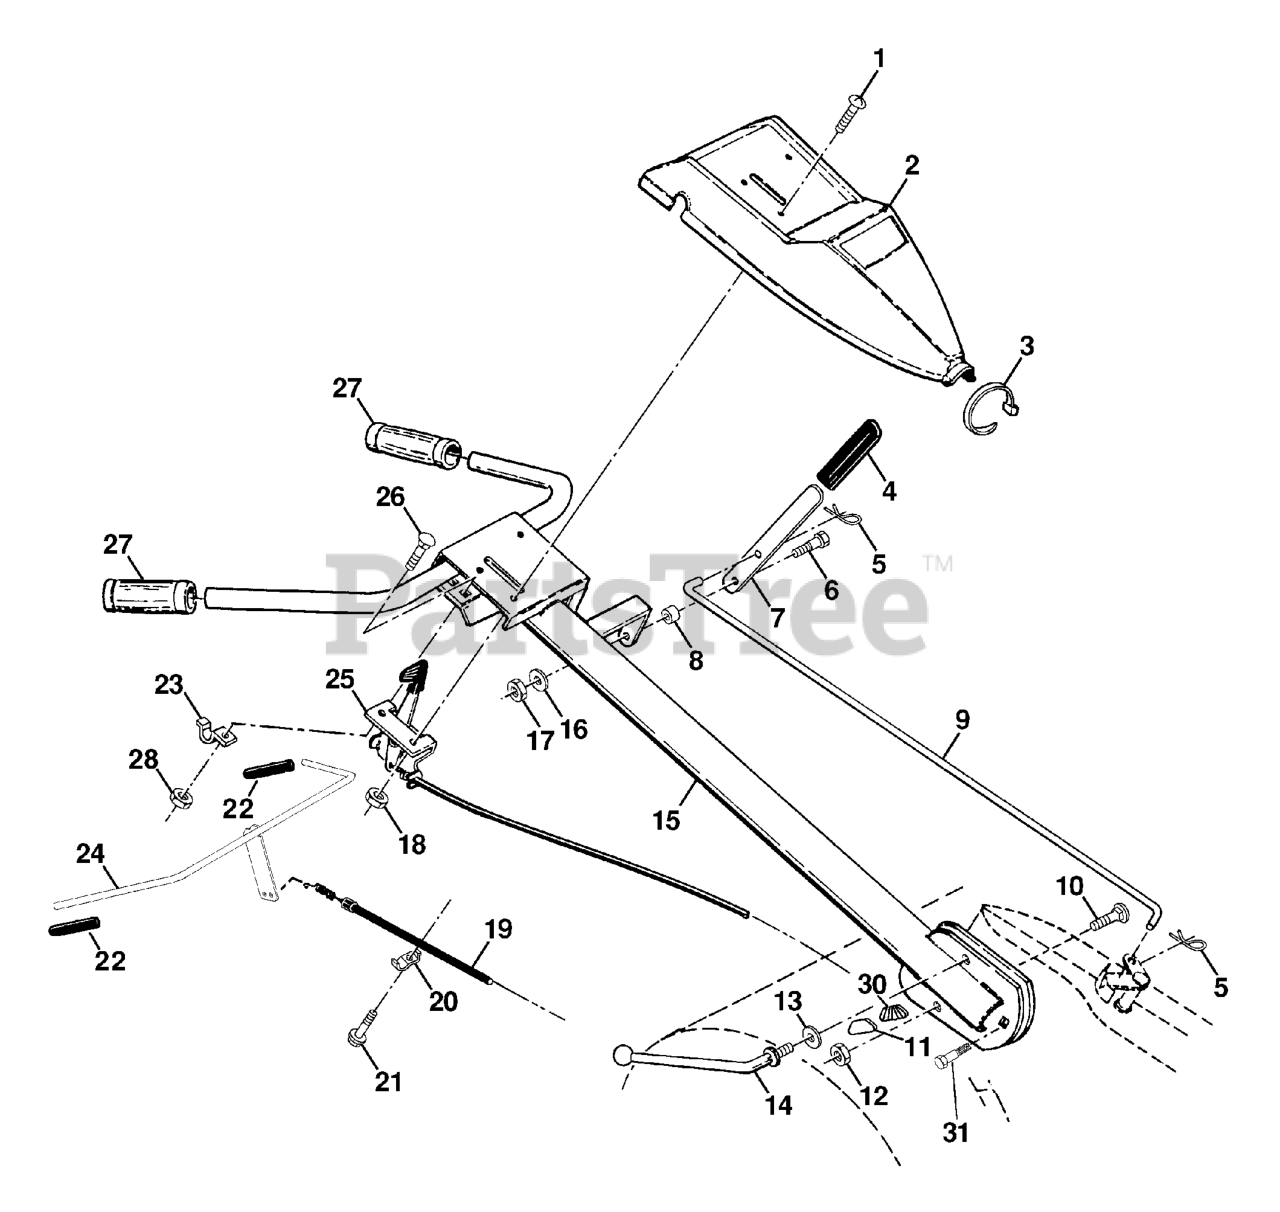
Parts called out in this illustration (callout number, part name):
1	SCREW.PNHD.10-24
3	TIE CABLE CRT
4	GRIP T
5	RETAINER M
6	SHOULDER BOLT ST
7	SHIFT HANDLE CRT
8	GROMMET.RUBBER.CRT.TILLER
9	ROD.SHIFT.YARD PRO.UNIVERSAL.
10	BOLT D
11	LOCK.HANDLE.CRT
12	LOCKNUT
13	WASHER CRT
14	LEVER.LOCK.CRT
15	HANDLE
16	LOCKWASHER
17	NUT
18	NUT **
19	CABLE.CLUTCH
20	CONDUIT.CLIP.PLATED
21	TAPPING SCREW
22	GRIP BAR CRT(1)
23	CLAMP.BAR.CRT.BLACK
24	CONTROL BAR ASSY
25	THROTTLE CONTROL
26	BOLT
27	KIT.GRIP.HANDLE.5.00.BLK.VINYL
28	NUT
29	BOLT.PIVOT
30	LOCK HANDLE
